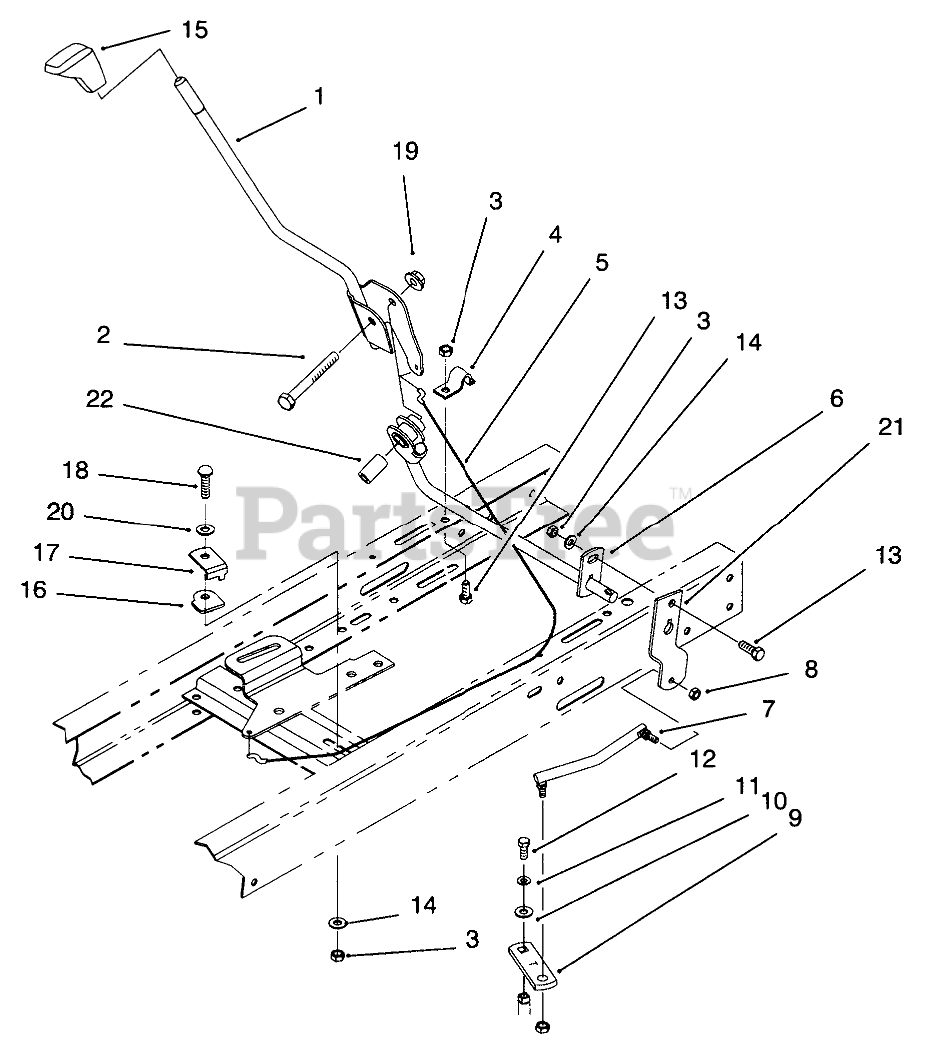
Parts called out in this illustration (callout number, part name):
1	Lever-Shift
2	SCREW-HH
3	NUT-LOCK, NI
4	CLAMP-PIVOT, SHIFT
5	CABLE-CLUTCH
6	Pivot-Shift
7	LINK-SHIFT
8	NUT-LOCK
9	LEVER-SHIFT
10	SPACER
11	WASHER-LOCK
12	SCREW-HH
13	SCREW-HH
14	WASHER-PLAIN
15	KNOB-SHIFT
16	GUIDE-CABLE
17	KEEPER-CABLE
18	SCREW-CARR
19	NUT-LOCK, NI
20	WASHER-FLAT
21	LEVER-PIVOT, SHIFT
22	BUSHING-SHIFT, LEVER
